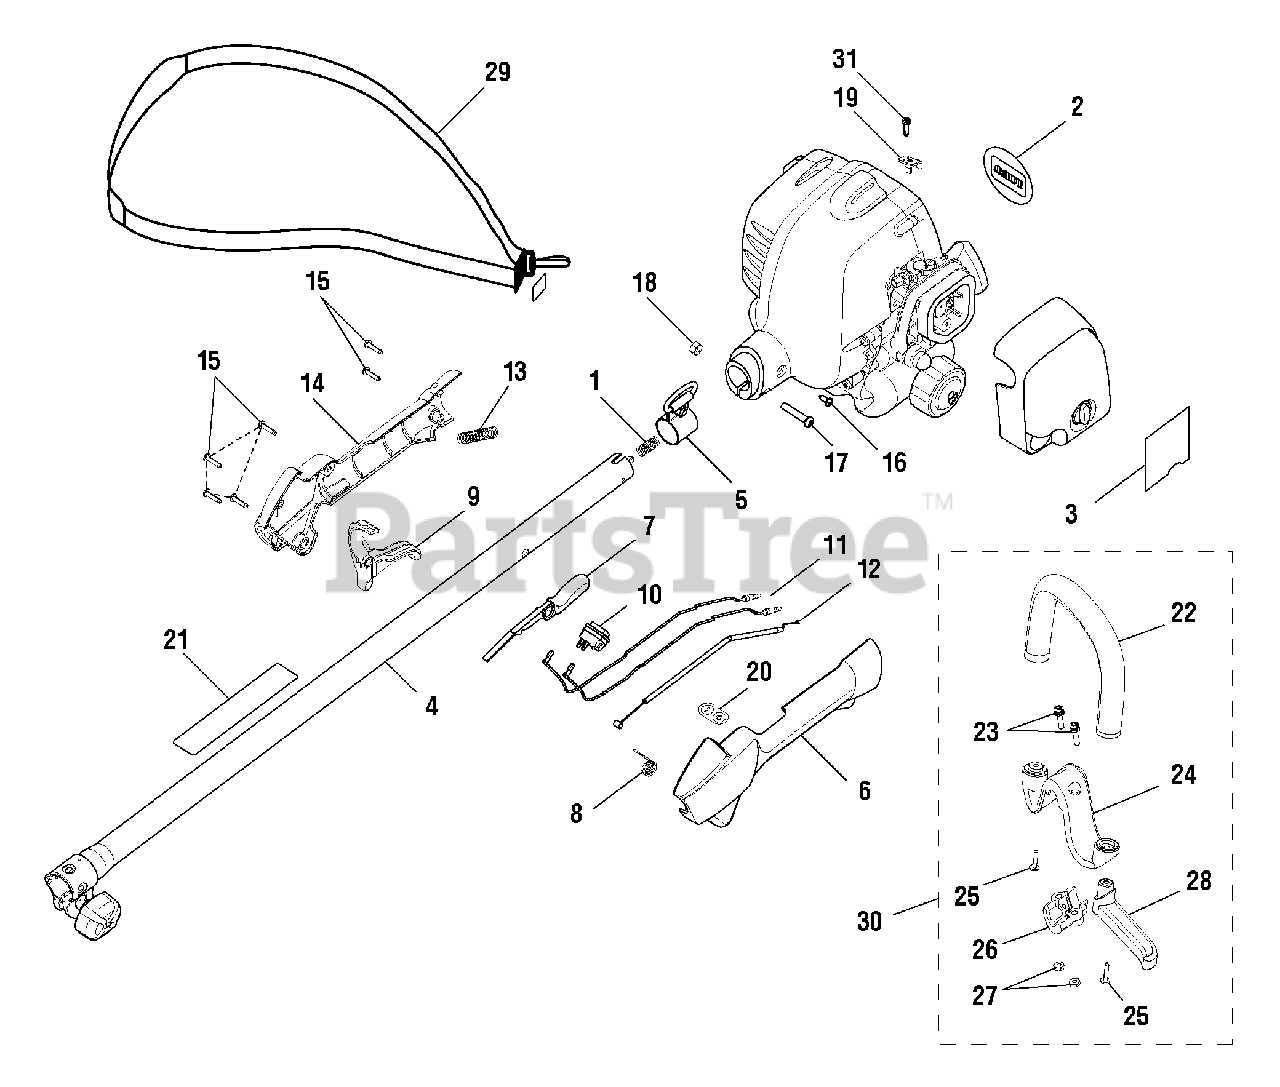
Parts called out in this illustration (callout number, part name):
1	COMPRESSION SPRING
2	LOGO PLATE
3	LOWER START LABEL
4	UPPER SHAFT ASSEMBLY(INC. KEY NO. 21)
5	HANGER BRACKET
6	REAR HANDLE SUPPORT
7	LOCK-OFF BUTTON
8	TRIGGER SPRING
9	TRIGGER
10	SWITCH WITH DUST SHIELD
11	LEAD
12	CABLE, THROTTLE
13	CORRUGATED TUBE
14	REAR HANDLE COVER
15	SCREW (M4 X 16 mm)
16	SCREW (#8-16 X 1/2 in.TRI-LOBULAR)
17	SCREW (M6 X 1-30 mm)
19	THROTTLE CABLE CLAMP
20	ON/OFF LABEL
21	WARNING LABEL
22	ASSIST HANDLE W/GRIP
23	SCREW (#12-24 X 1 in.)
25	SLOTTED TORX SCREW
26	CLAMP
27	HEX NUT (12-24)
28	BARRIER BAR
29	HARNESS ASM. W/LABEL
30	ASSIST HANDLE W/BARRIER
31	SCREW (M4 X 16 mm)
